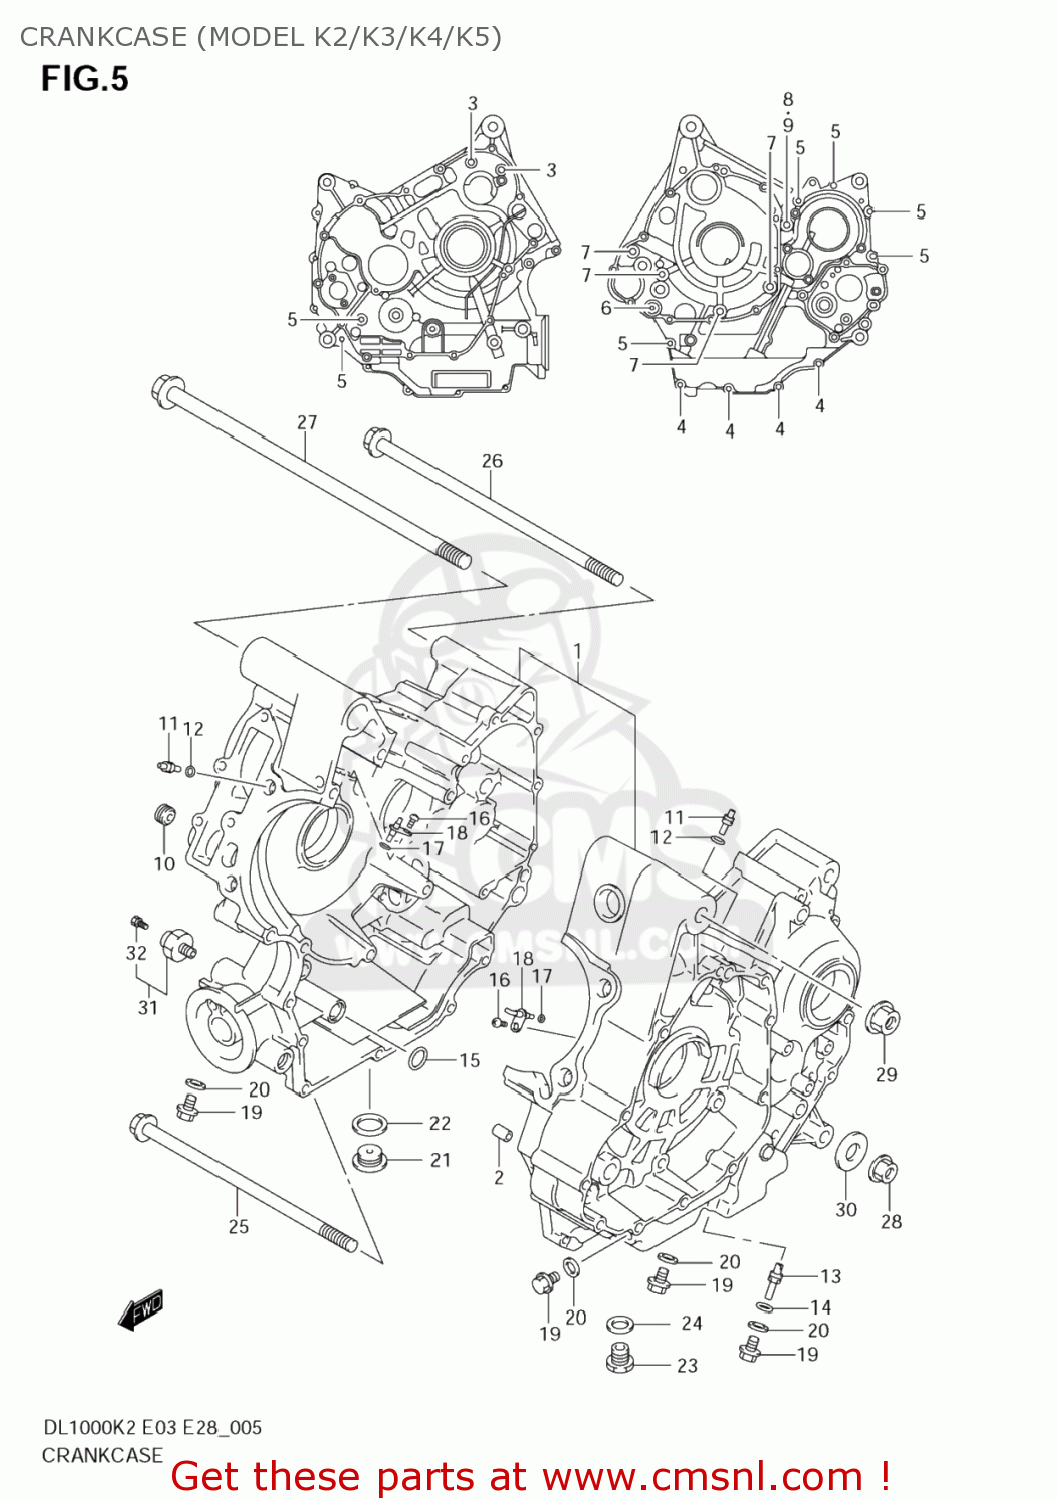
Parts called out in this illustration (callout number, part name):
1	CRANKCASE SET
2	PIN,CRANKCASE
3	BOLT(8X110)
4	BOLT,G/S SWITC
5	BOLT
6	BOLT, CRANKCASE (6X85)
7	BOLT
8	BOLT(8X125)
9	WASHER
10	JET,OIL GALLERY(3.6)
11	JET,OIL GALLERY
12	O RING(D:1.2,ID:4)
13	JET,OIL GALLERY
14	O RING(D:1.2,ID:4)
15	O RING(D:1.9,ID:12.6)
16	BOLT(6X12)
17	O RING(D:1.2,ID:4)
18	JET,PISTON COOLING
19	BOLT
20	GASKET(8.2X14X1) (NAS)
21	PLUG,16X8
22	GASKET(16X22X2) (NAS)
23	PLUG(14X20)
24	GASKET(13.8X18.8X4.8) (NAS)
25	BOLT(10X225)
26	BOLT(10X265)
27	BOLT(12X320)
28	NUT
29	NUT
30	WASHER(10.5X22X2.3)
31	SWITCH ASSY,OIL PRESSURE
32	BOLT,OIL PRESSURE SWITCH
